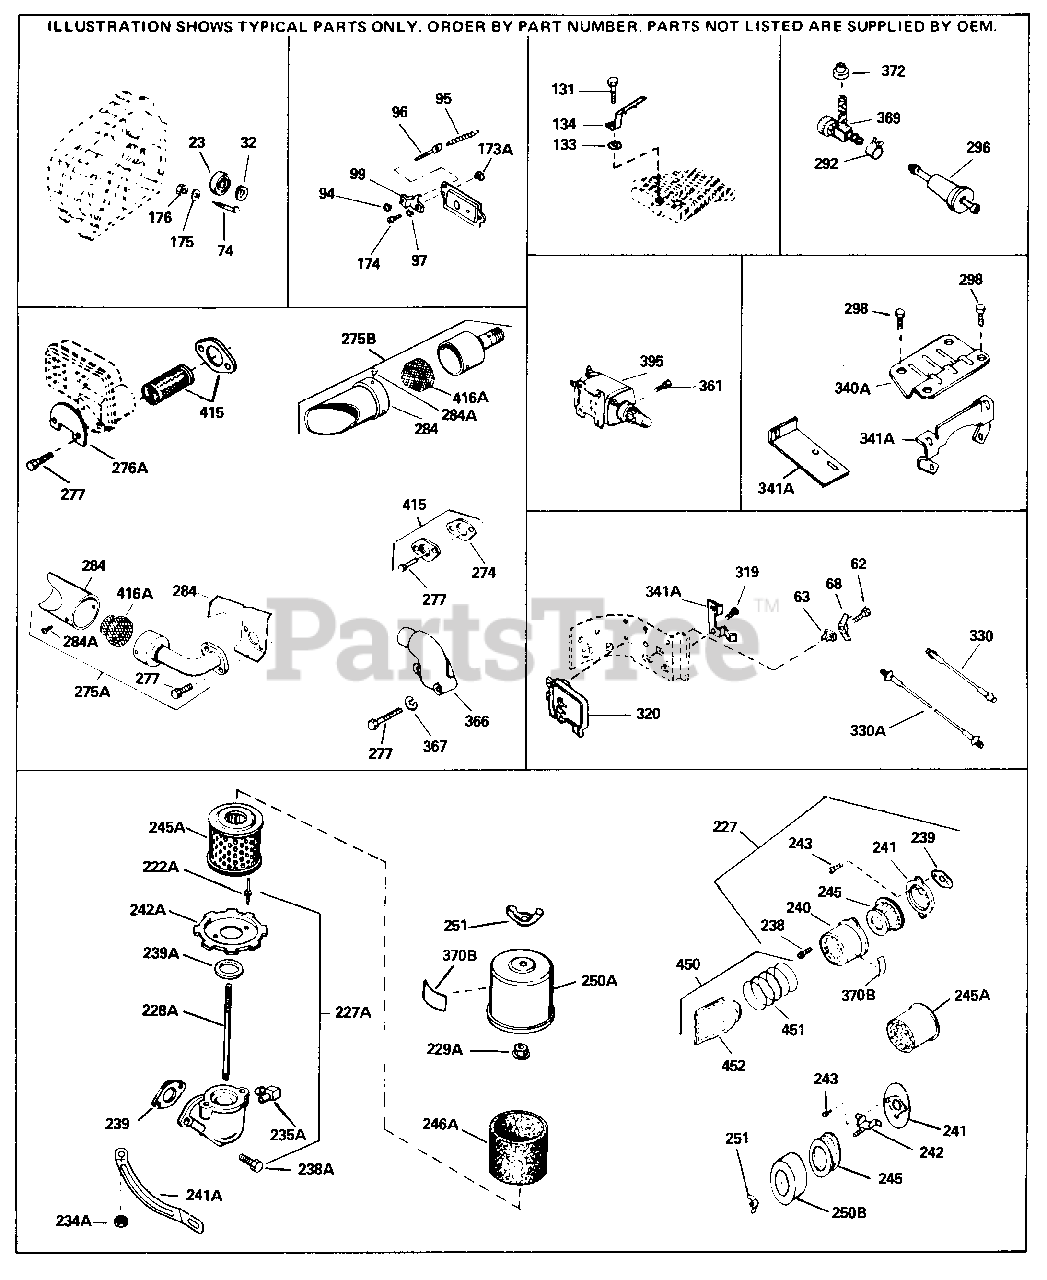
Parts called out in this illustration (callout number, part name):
62	Screw, 8-32 x 3/8"
63	Breather Tube Grommet
68	Terminal, Ground
74	Retainer, Bearing
94	Nut Lock, 10-32
95	Spring, Extension
96	Bolt, Governor spring adjusting
97	Lockwasher, Heavy split, #10 Buy loc ally
131	Screw, 1/4-20 x 1/2" Use as required
131	Screw, 1/4-20 x 5/8" Use as required
133	Washer, Lock, 5/16"
134	Clip, Spark plug shorting
174	Screw, 10-24 x 1/2"
174	Screw, 10-24 x 5/8"
227	Air Cleaner Ass'y. (Incl. 238,239,240 ,241,243,245 & 370) (Use as required)
227	Air Cleaner Ass'y. (Incl. 238, 239, 2 40, 241, 243 & 245) (Use as required)
228A	Stud, 1/4-20 x 7.33 (Use as required)
228A	Stud, 1/4-20 x 8.1 (Use as required) (Used with drilled thru elbow)
239	* Gasket, Air cleaner
241	Bracket, Air cleaner
242	Bracket, Air cleaner
243	Screw, 10-32 x 1/2"
245	Air Filter (Paper) also available in Packaged Part #740027B
245A	Air Filter
250B	Cover, Air cleaner
251	Nut, Wing, 1/2-20
274	Gasket, Exhaust (Use as required)
275B	Muffler (Incl. 284, 284A & 416A) (Thi s spark arresting muffler can be used on any model.)
275C	Muffler (Optional quiet muffler)
276A	Spark Arrester Kit (Incl. 277A) (Also as an optional part)
277	Screw, 5/16-18 x 3-3/16"
277A	Screw, 5/16-18x2-3/4" Used with 276A
292	Fuel Line Clamp
298	Screw, 1/4-15 x 7/8"
361	Screw, T-30, 1/4-20 x 1/2"
370B	Decal, Instruction Can be used on HM8 0 with stamped steel recoil starter.
370J	Decal, Instruction Can be used on HM8 0 with diecast starter.
395	Starter Motor Kit (110-120 Volt) This 110-120 volt starter motor kit may h ave been added to this engine. It can be added only if cylinder hasdrilled and tapped starter mounting bosses a nd a ring gear flywheel. Refer to se rvice number stamped on e
395	Electric Starter Motor (12 Volt) (Inc l. 361) (Refer to service number stam ped on end cap of motor, or on decal for identification. Refer to Divisio n 5, Section D, Page 20 for breakdown or Fiche 18A-1, Grids G-9, G-10 or G -11)
408	Screen Seal Can be used on HM80 with stamped steel recoil starter
409	Spacer Can be used on HM80 with stamp ed steel recoil starter
410	Debris Screen Kit (Incl. 360, 370B, 3 87, 411 &413) (Can be used on HM80 wi th stamped steel recoil starter)
411	Debris Screen Can be used on HM80 wit h stamped steel recoil starter
413	Screw, 5/16-18 x 1-5/8" Can be used o n HM80 with stamped steel recoil star ter
415	Exh.Adapter Kit (Incl. 274,277) Use a s req.
425	Starter Muff Kit (Incl. 370J, 426 & 4 27) (Can be used on HM80 with di e cast starter)
429	Screw, 8-18 x 1-1/8" (3 Required) (Us e as required) (Refer to Mechanics Ha ndbook for installation instructions) .
430	Alternator, Add on (Use as required) (Refer to Mechanics Handbook for inst allation instructions).
431	Centering tube (Use with engines equi pped with die cast aluminum starter)( Use as required) (Refer to Mechanics Handbook for installation instruction s)
431	Centering tube (Use as required) (Ref er to Mechanics Handbook for installa tion instructions).
432	A.C. Lighting Connector (Use as requi red) (Refer to Mechanics Handbook for installation instructions).
432	D.C. Charging Connector (Use as requi red) (Refer to Mechanics Handbook for installation instructions).
433	Alternator Shaft (4.00") (Use with en gines equipped with cast aluminum sta rter)(Use as required) (Refer to Mech anics Handbook for installation instr uctions).
433	Alternator Shaft (Use with engines e quipped with stamped steel starter)(U se as required) (Refer to Mechanics H andbook for installation instructions ).
